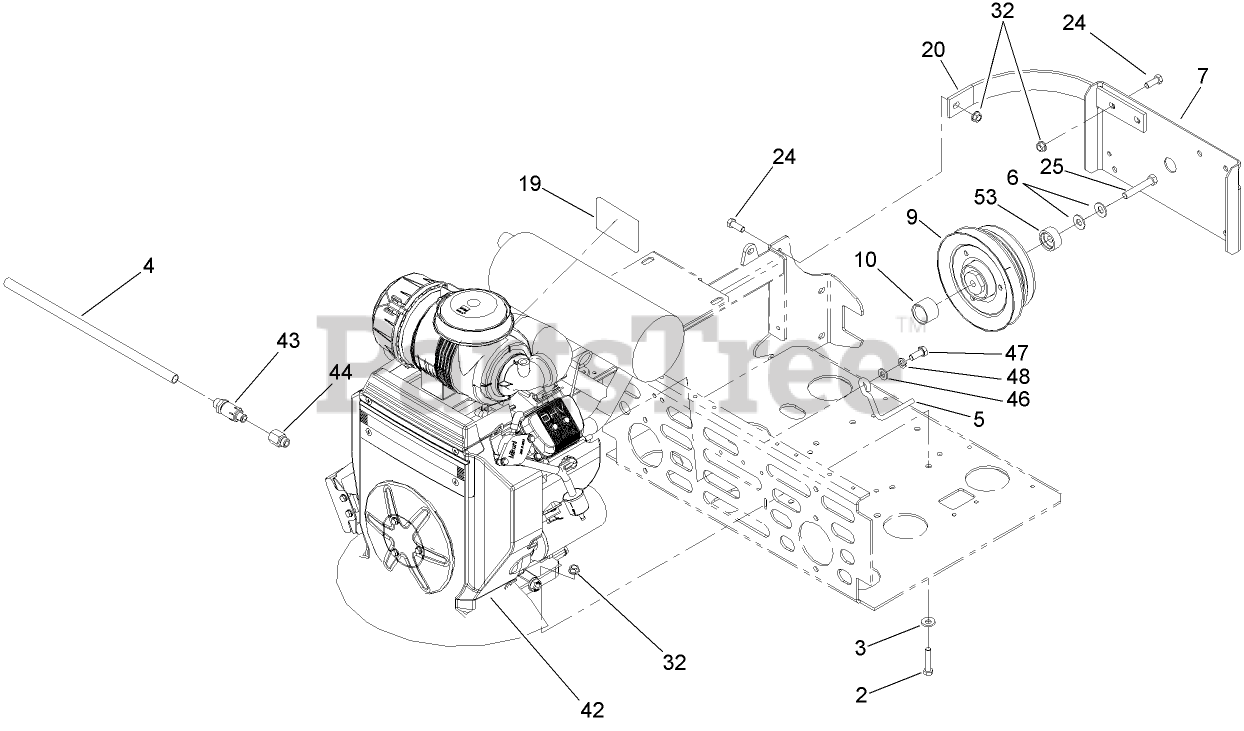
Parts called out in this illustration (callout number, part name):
2	SCREW-HH
3	WASHER-BELLEVILLE
4	TUBE-DRAIN, OIL
5	ROD-BELT
6	WASHER-SPRING
7	GUARD-CLUTCH
9	CLUTCH
10	SPACER-CLUTCH
20	STRAP-GUARD
24	SCREW-HH
25	SCREW-HH
32	NUT-HHF, WHIZ
43	VALVE-DRAIN, OIL
44	Adapter
46	WASHER-FLAT
47	SCREW-HH
48	WASHER-BELLEVILLE
53	KEEPER-CLUTCH
